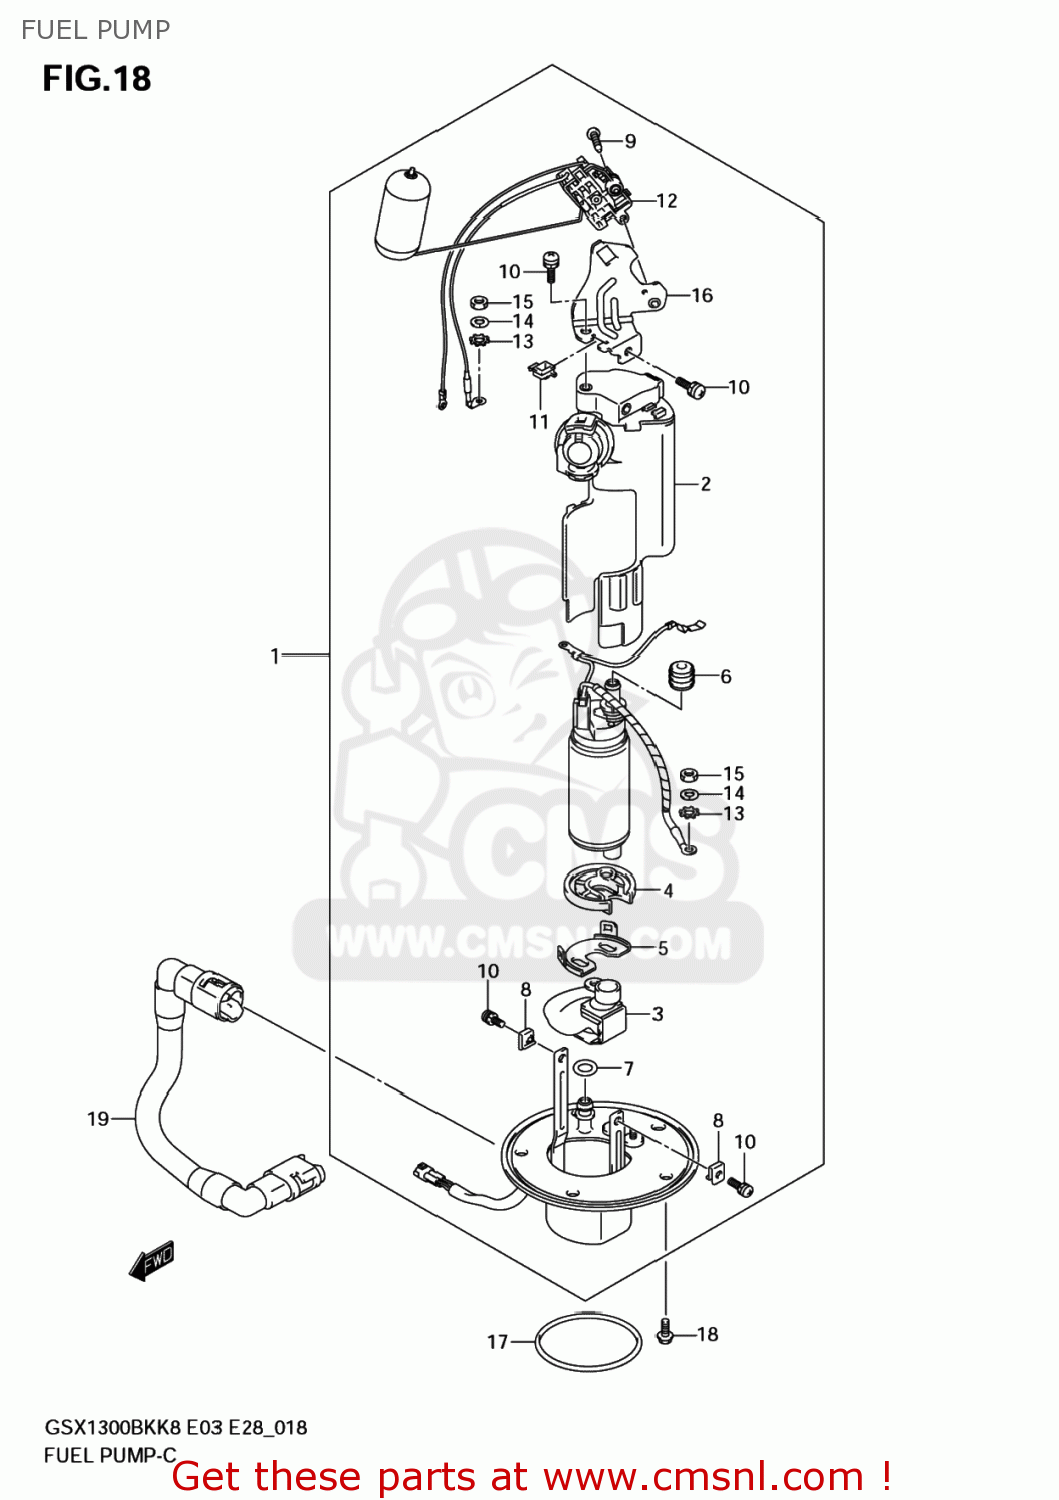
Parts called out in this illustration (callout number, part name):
1	PUMP ASSY,FUEL
2	FILTER,FUEL
3	STRAINER,FUEL
4	CUSHION
5	HOLDER,FUEL PUMP
6	BUSH,FUEL PUMP
7	O RING
8	NUT
9	SCREW
10	SCREW
11	SADDLE,EDGE
12	GAUGE ASSY,FUEL LEVEL
13	WASHER
14	WASHER,SPRING
15	NUT
16	BRACKET,FUEL GAUGE
17	O RING,FUEL PUMP
18	BOLT
19	HOSE,FUEL
